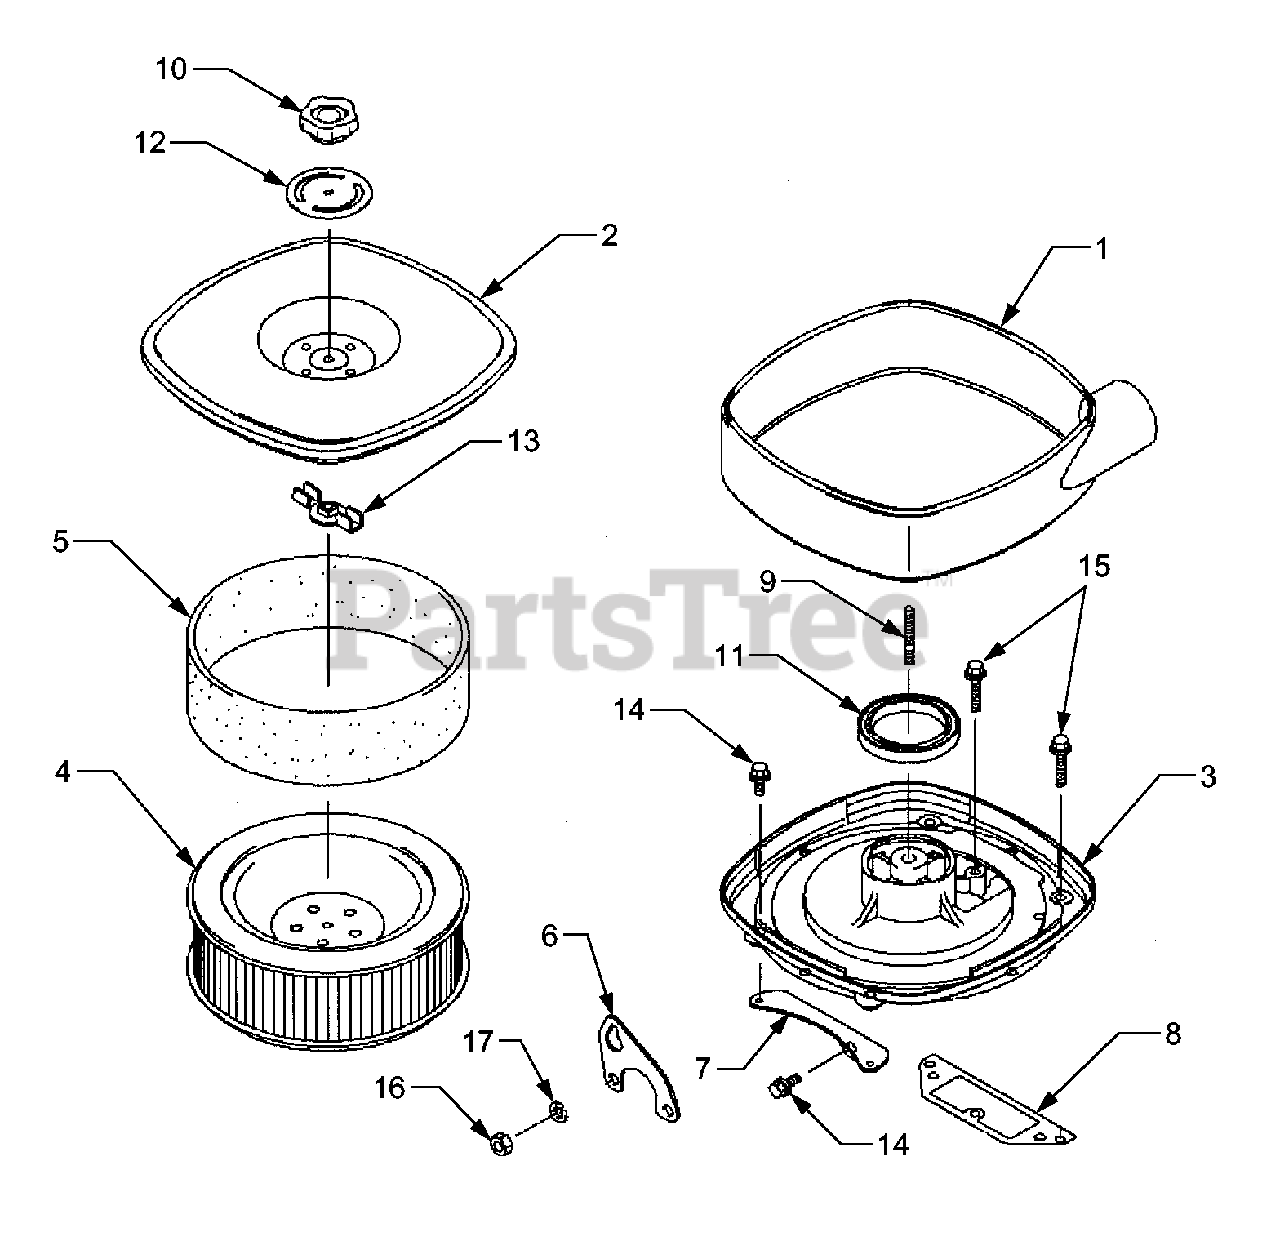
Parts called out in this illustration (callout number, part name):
1	Case, Air Filter Body
2	Case, Air Filter Upper
3	Case, Air Filter Lower
4	Element, Air Filter
5	Precleaner, Foam
7	Bracket, Air Filter
8	Gasket, Air Filter
11	Seal
14	Bolt, Flanged
15	Bolt, Flanged
17	Washer, Spring
